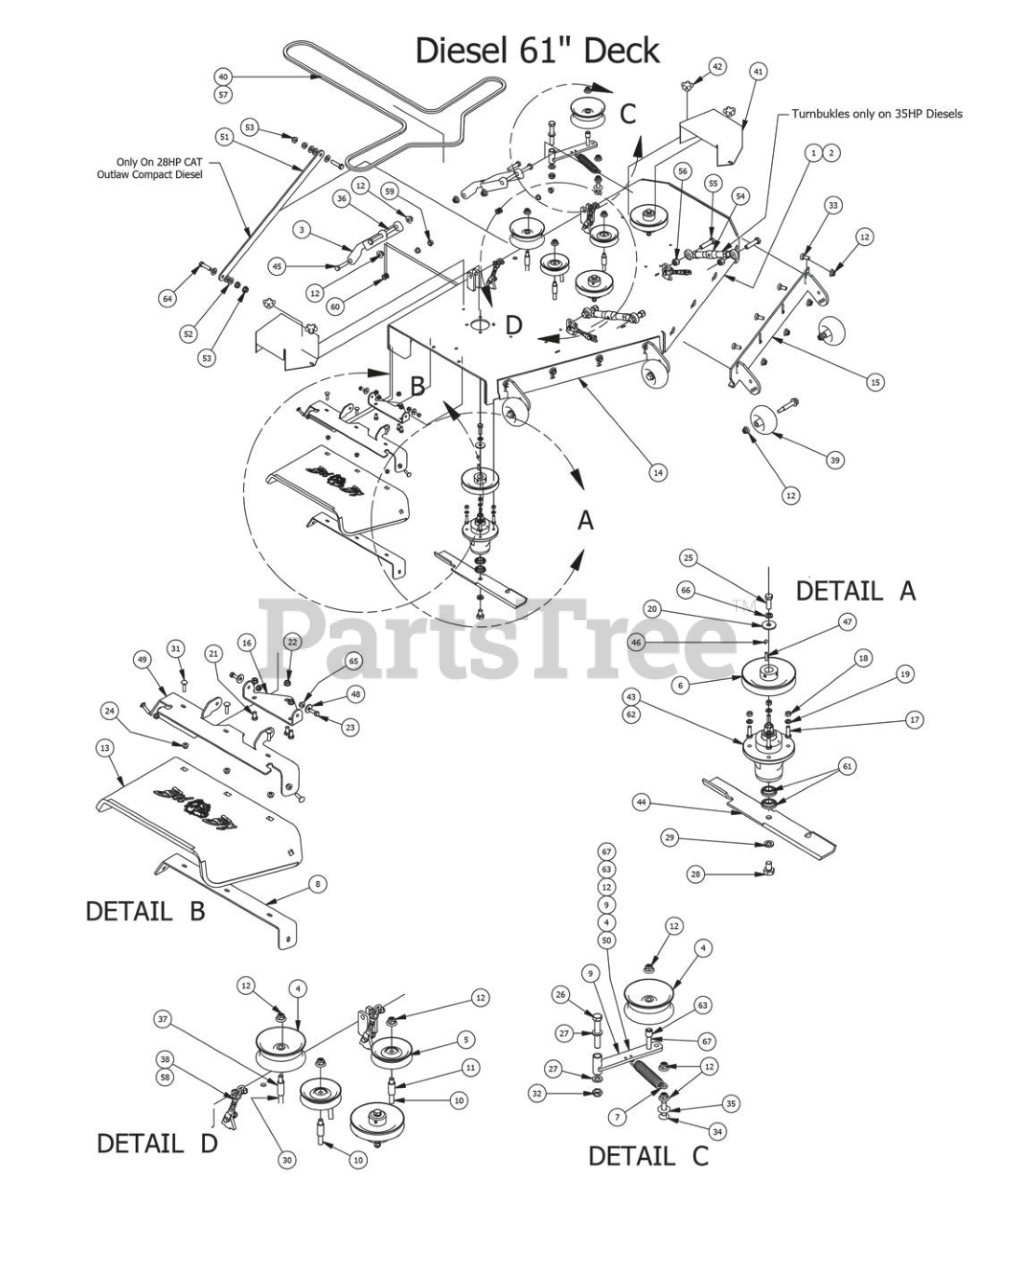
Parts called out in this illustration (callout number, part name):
1	61" Outlaw Deck Only 28HP Diesel
2	61" AOS Deck Only 2012 35Hp Diesel
3	Deck Arm Assembly
4	5 3/4" Deck Idler Pulley
5	4 3/4" Idler Pulley
6	6 1/4" Drive Pulley
7	2009 Deck/Pump Idler Spring
8	60" Discharge Lower Bracket
9	Deck Idler
10	1/2 x 3 1/2 Flange Bolt Grade 8
11	502 ID X.75 OD X 1.500 Leng
12	1/2-13 Nylon Insert Flange Nut
13	Rubber Discharge Chute
14	61 Outlaw Adjustable Deck Front (Left)
15	61 Outlaw Adjustable Deck Front (Right)
16	Discharge Chute Hanger (deck mounted)
17	3/8" x 1 1/4" Hex Bolt
18	3/8-16 Hex Nuts Zinc
19	3/8 Lockwasher Zinc
20	1/2 Belleville Washer
21	3/8" x 3/4" Hex Bolt
22	3/8" Flange Nut
23	5/16" x 1" Bolt
24	5/16" Flange Nut Zinc W/Serrations
25	1/2"-20 x 1 1/2- Grade 5 Fine Thread Bolt
26	5/8" x 4" Hex Bolt
27	.635 ID Plastic Washer
28	5/8" x 1 1/2" Grade 8 Bolt
29	5/8" Lock Washer
30	1/2" x 4" Bolt (Grade 8)
31	5/16" x 1 1/4" Carriage Bolt
32	5/8-11 Nylon Insert Jam Half Nut
33	1/2" x 1 1/4 Carriage Bolt
34	1/2 x 2" Carriage Bolt
35	1/2" Flat Washer
36	1/2" x 5 1/2" Bolt
37	1 3/4" Pulley
38	4-Link Adjustable Deck Hange 35HP Diesel
39	Deck Wheel
40	B226 Belt For 2012 (61" 28HP Compact Diesel Only)
41	Pulley Cover
42	5/16" Knob
43	Double Bearing Spindle Only on 28hp Diesel
44	61 inch Fusion Blade
45	1/2-13X 2-1/4 GR Hex Bolts
46	5/16 Set Screw
47	1/4" x 1" Key
48	360 ID Plastic Washer
49	60" Discharge Chute Upper Hanger
50	Deck Idler Assembly-parts of Assembly 4,9,12,63,67
51	Panhard Linkage Bar
52	.505 Nylon Spacer
53	1/2" Flange Nut
54	Turnbuckle (Top Link)
55	5/8" x 2 1/2 Hex Bolt
56	5/8 Std NC Nylock Nut
57	B236 Belt Diesel EZ Ride 35Hp (61" Diesel only)
58	3 Link Adjustable Deck Hanger only on 28HP Diesel
59	Flange Bushing For Deck Arm upper
60	Flange for Lower Deck Arm
61	Double Bearing For Spindle
62	Double Bearing Spindle Only on 35hp Diesel
63	3/4 OD x 1/2 ID x 3\4 Length
64	1/2-13x2 Grade 8 Hex Bolt
65	5/16 Nylon Flange Nut
66	1/2" Lock Washer
67	1/2-13 x GR 5 Hex Bolt Zinc
